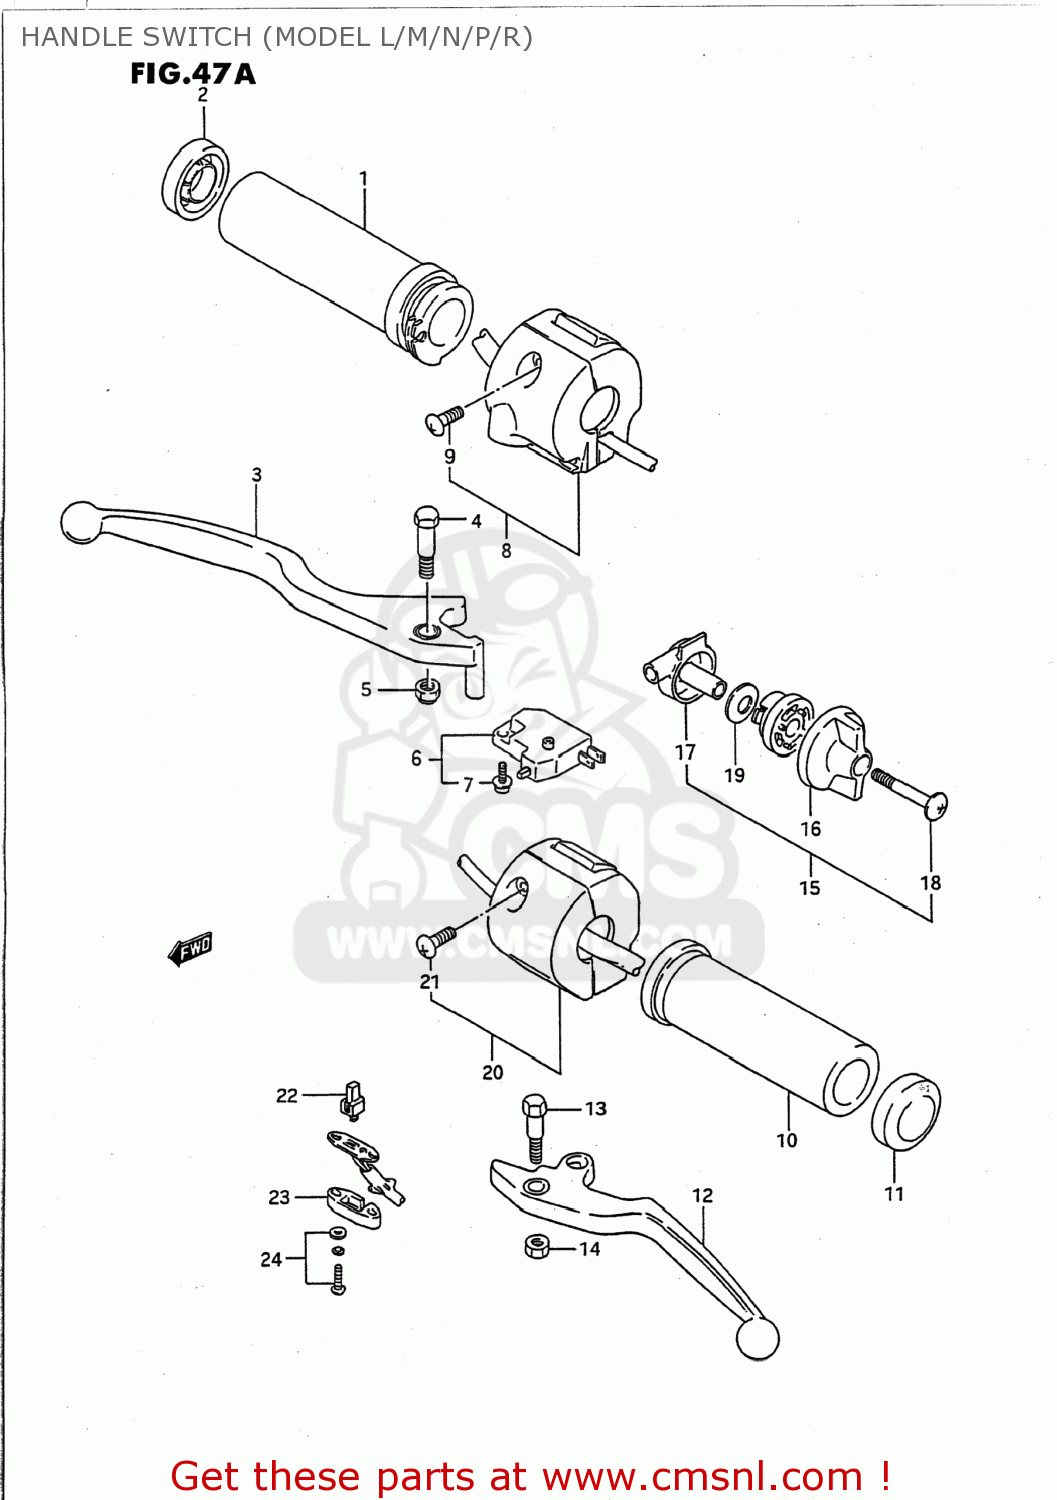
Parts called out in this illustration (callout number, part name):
1	GRIP,THROTTLE
2	CAP,GRIP END
3	LEVER,BRAKE
4	BOLT,LEVER
5	NUT 6MM
6	SWITCH ASSEMBLY,STOP
7	SCREW
8	SWITCH ASSY,HANDLE,R
9	SCREW
10	GRIP,L
11	CAP,GRIP END
12	LEVER,CLUTCH
13	BOLT,LEVER
14	NUT 6MM
15	LEVER ASSEMBLY,STARTER
16	CLAMP,REAR BRAKE CABLE
17	BODY,STARTER
18	SCREW,STARTER LEVER(6X45)
19	WASHER
20	SWITCH ASSY,HANDLE,L
21	SCREW
22	CONTACT,SWITCH
23	COVER,CLUTCH SWITCH
24	SCREW
